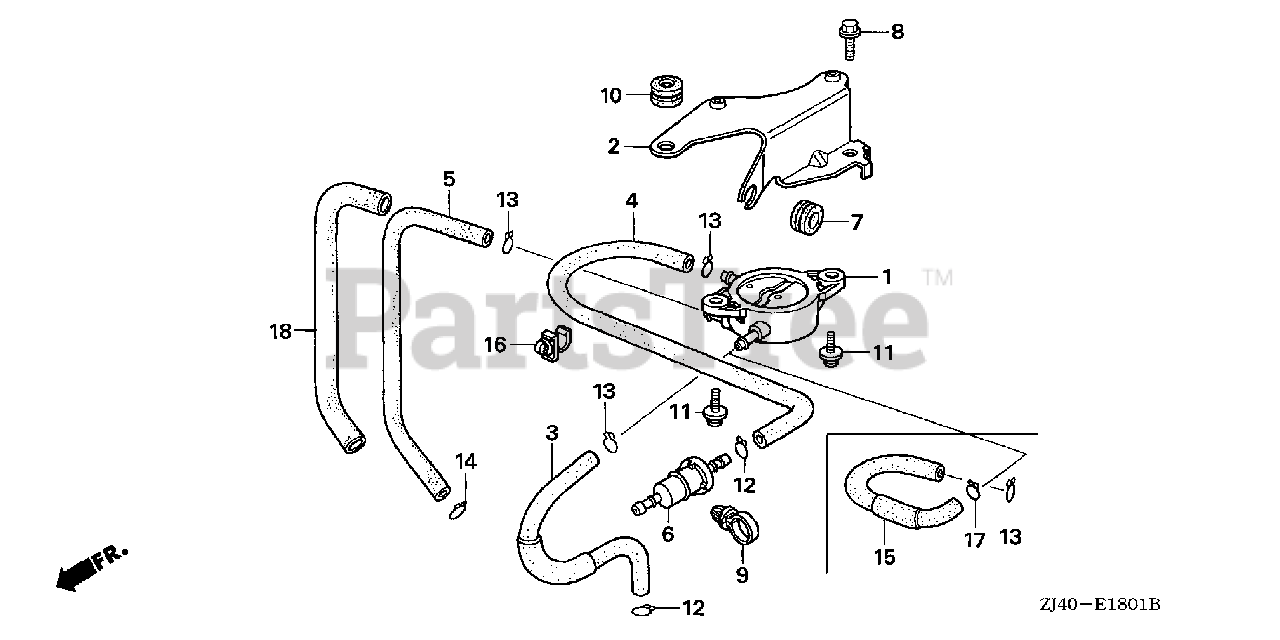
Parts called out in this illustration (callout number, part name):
1	PUMP ASSY., FUEL
2	STAY, FUEL PUMP
3	TUBE A, FUEL
4	TUBE B, FUEL
5	TUBE, DIAPHRAGM
6	STRAINER, FUEL
7	GROMMET, RESERVE TANK
8	BOLT, FLANGE (6X14) (CT200)
9	CLIP, WIRE HARNESS
10	GROMMET, PUMP STAY
11	SCREW-WASHER (6X16)
12	CLIP, TUBE (B8)
13	CLIP, TUBE (B10)
14	CLIP, TUBE (C9)
18	BULK HOSE, VINYL (9X11X3000) (9X11X150)
